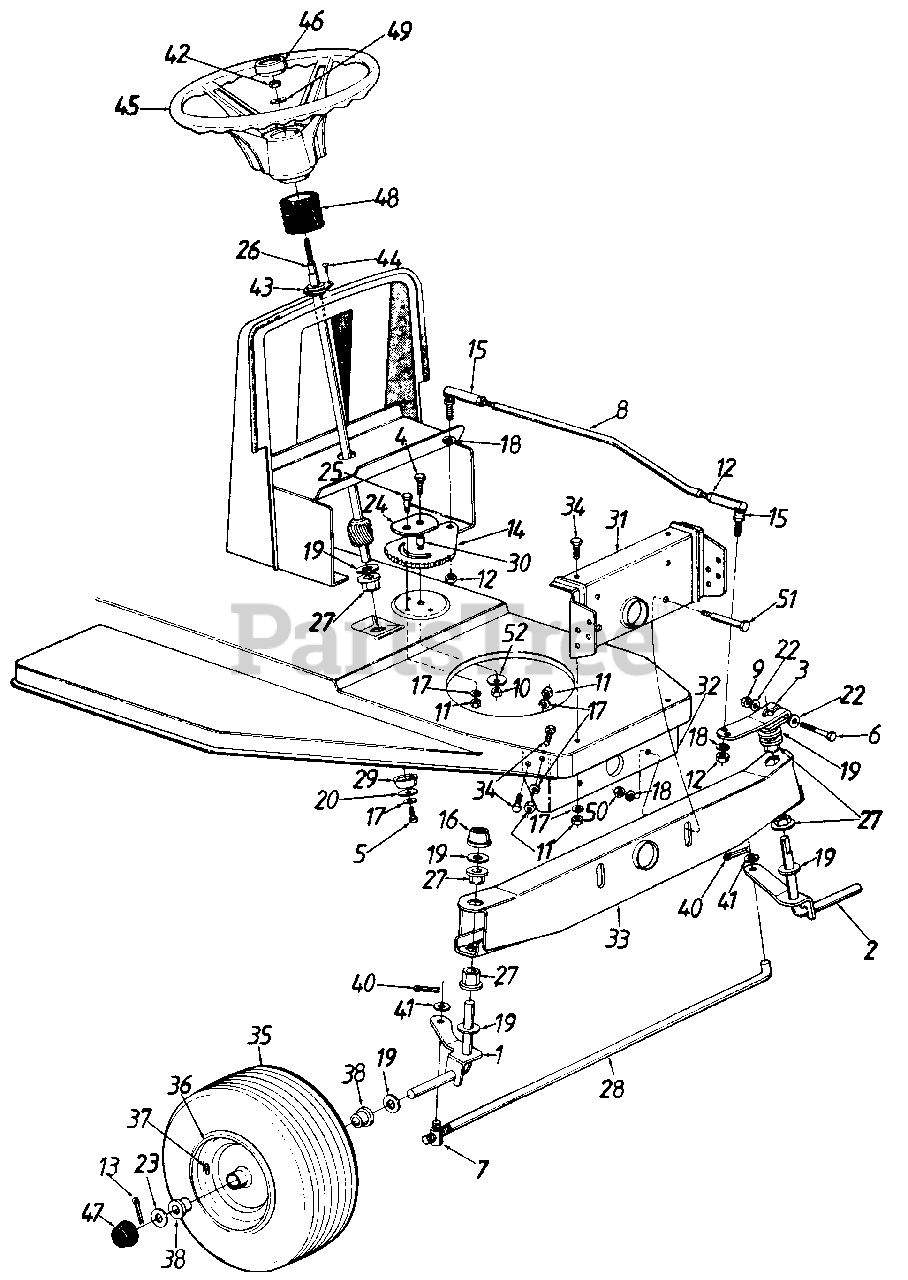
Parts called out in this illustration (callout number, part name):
1	Front Axle Ass'y.-R.H.
2	Front Axle Ass'y.-L.H.
3	Steering Arm
4	Hex Bolt 3/8-24 x 1" Lg.*
5	Hex Bolt 5/16-18 x .62"
6	Hex Bolt 5/16-24 x 2" Lg.
7	Ferrule
8	Steering Drag Link
9	Hex L-Nut 5i16-24 Thd.
10	Hex Nut 3/8-24 Thd.
11	Hex Nut 5/16-18 Thd.
12	Hex Jam Nut, 3/8-24
13	Cotter Pin 1/8 Dia.
14	Steering Gear Segment
15	Drag Link Ball Joint 3/8-24 Thd.
17	L-Wash. 5/16" I.D.
18	L-Wash. 3/8" I.D.
19	Fl-Wash. .64" I.D. x 1.24"
20	Fl-Wash. .340" I.D. x 1.125"
22	Spr. Wash. .32 I.D. x .62
23	Fl-Wash. .635 I.D. x 1.585
24	Retainer Plate
25	Shld. Bolt .437 Dia. x .350
26	Steering Shaft
27	Hex Flange Brg. .634 Dia.
28	Tie Rod 19.1 Lg.
29	Spacer .985 I.D.
30	Spacer .380 I.D.
31	Front Pivot Bar Support Brkt.
32	Rear Pivot Bar Support Brkt.
33	Pivot Bar Ass'y.
34	Hex Bolt 5/16-18 x .75" Lg.
35	Front Wheel Ass'y. Comp. 1 3 x 6
37	Air Valve
38	Flange Bearing .632 I.D.
40	Cotter Pin 3/32" Dia.
41	Fl-Wash. .406" I.D. x .75"
42	Hex L-Nut 5/16-24 Thd.
43	Steering Column Brg.
44	Cr-Sunk Scr. #10 x 5/8" Lg.
45	Steering Wheel
46	Steering Wheel Cap
47	Hub Cap
48	Bellow Steering Column
49	Bell-Wash. .345 I.D. x .88
50	Hex Nut 3/8-16 Thd.
51	Shld. Bolt 1/2" Dia. x 2.32"
52	Bell-Wash. .39" I.D. x 1.4" O.D.
